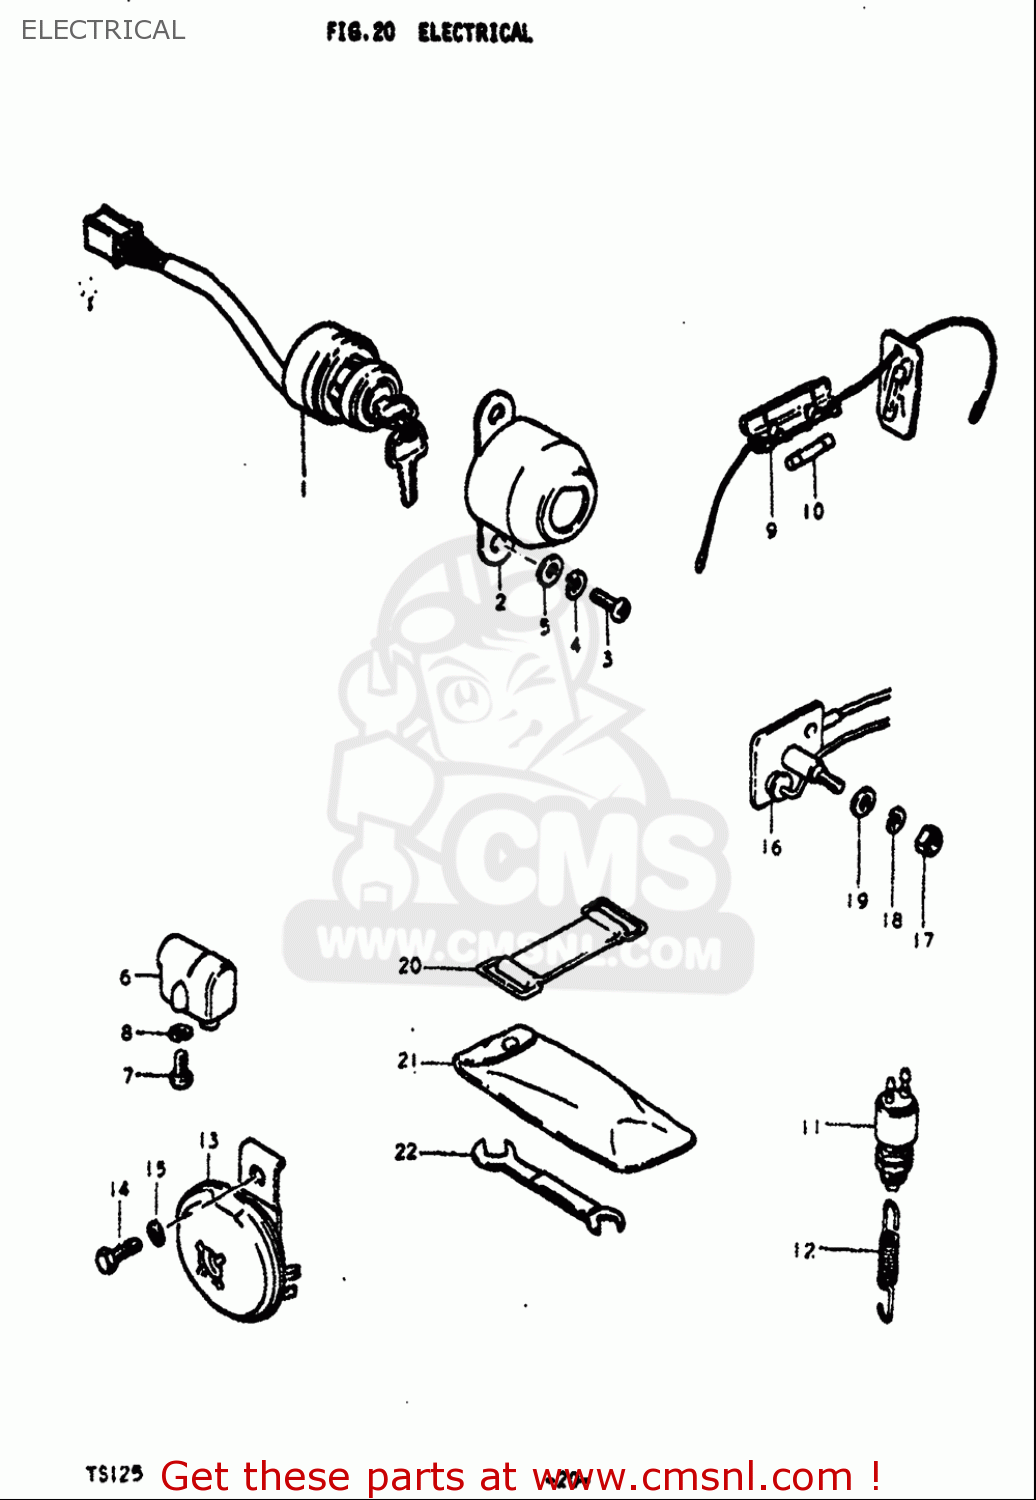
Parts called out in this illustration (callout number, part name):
3	SCREW
4	WASHER,LOCK
5	WASHER
6	LOCK ASSY,STEERING
7	SCREW
8	WASHER,LOCK
9	CASE ASSY,FUSE
10	FUSE(15A)
11	SWITCH ASSY,BRAKE LAMP
12	SPRING
14	BOLT
15	WASHER,LOCK
17	NUT
18	WASHER,LOCK
19	WASHER
20	BAND
21	TOOL ASSY
